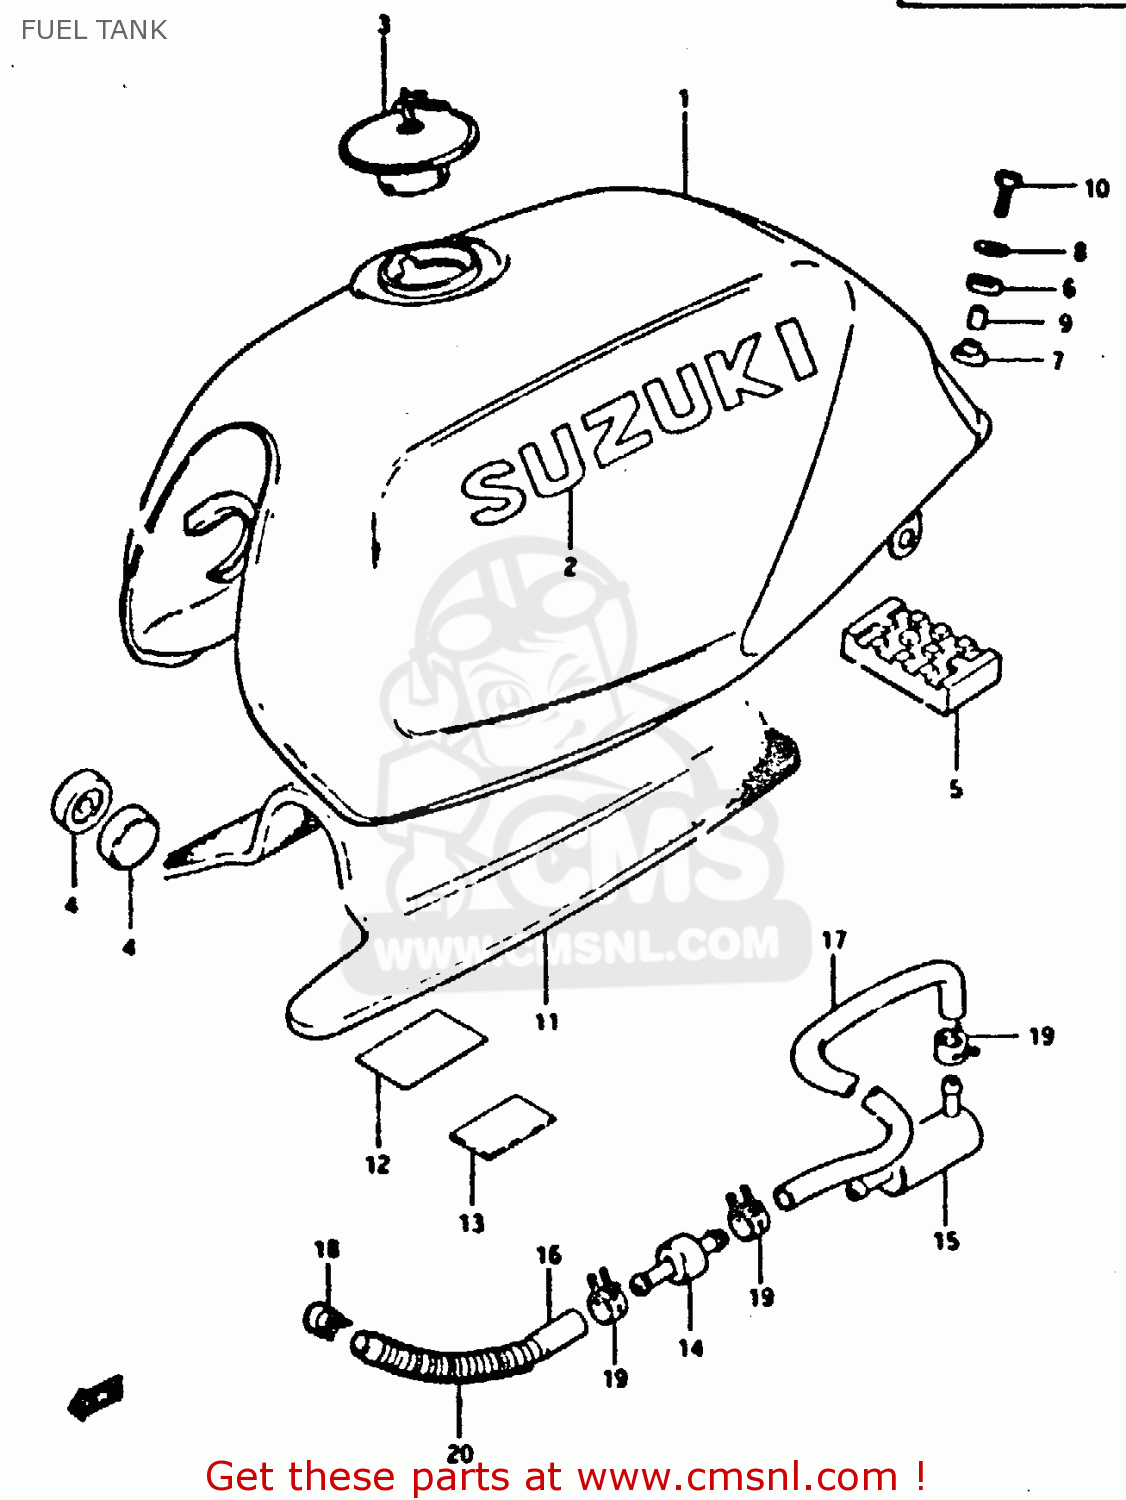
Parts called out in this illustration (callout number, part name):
1	TANK ASSEMBLY,FUEL
2	EMBLEM
3	CAP ASSEMBLY,FUEL TANK
4	CUSHION
5	CUSHION,FUEL TANK CTR
6	CUSHION
7	CUSHION
8	WASHER (6.5X24X1.6)
9	SPACER
10	BOLT
11	CUSHION, FUEL TANK INNER
12	TAPE,FUEL TANK CUSHION
13	PLATE,FUEL TANK CUSHION
14	CHECK VALVE,BREATHER
15	CANISTER, BRETHER HOSE
16	HOSE
17	HOSE
18	CLAMP
19	CLAMP
20	SPRING
